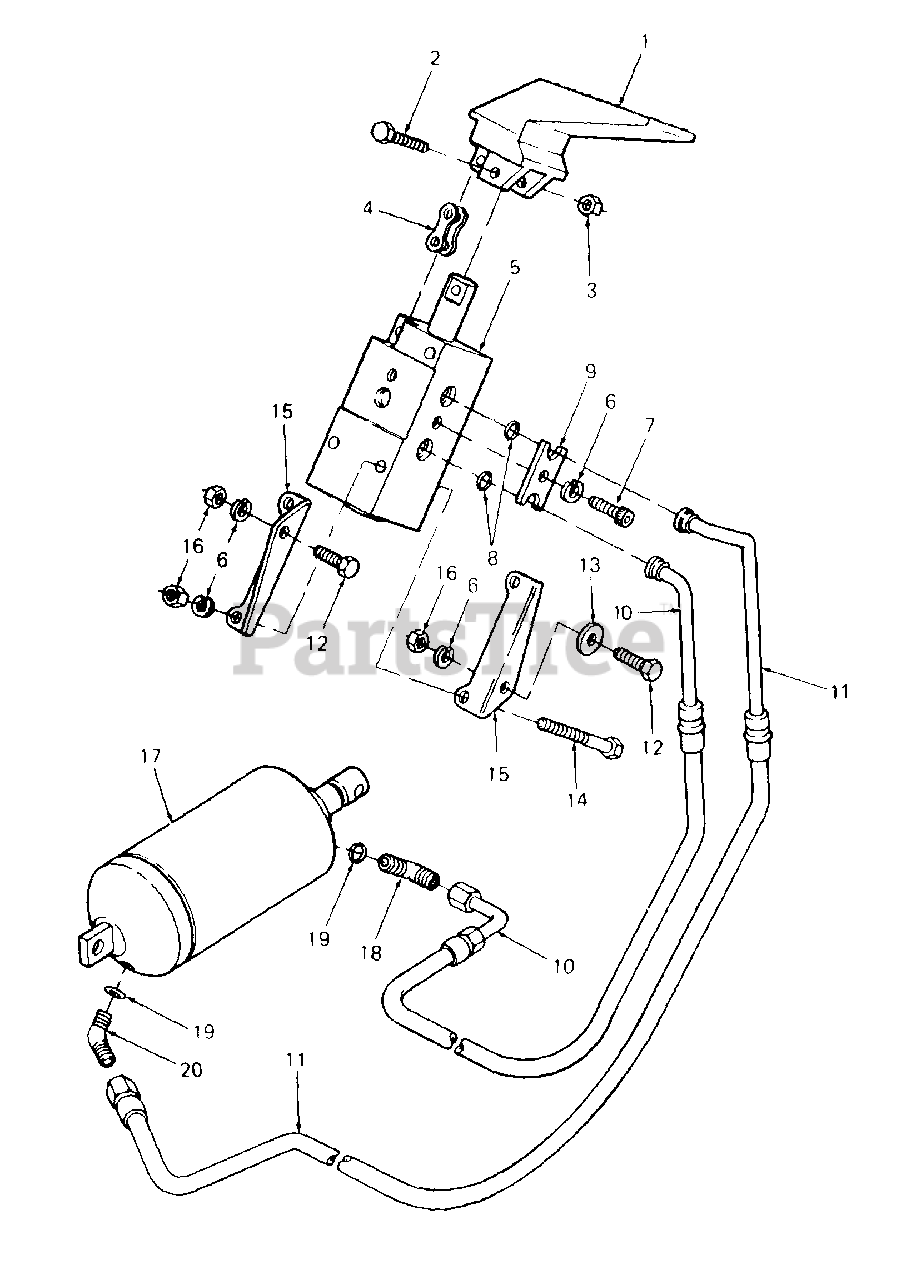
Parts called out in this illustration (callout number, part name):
1	Handle, Valve
2	Screw, Hex Cap, #10-24 X 1.0 Lg
3	Nut, Hex Center Lock, #10-24
4	Link, Chain
5	Valve, Lift
6	Washer, Lock, 1/4
7	Screw, Socket Hd Cap, 1/4-20 X .62 Lg GR8
8	O-Ring, .301 X .070 Dia
9	Clamp, Double
10	Hose, Cylinder-Contracting
11	Hose, Cylinder-Extending
12	Screw, Hex Cap, 1/4-20 X .62 Lg GR5
13	Washer, Bell, .265 X .75 X .62 Thk
14	Screw, Hex Cap, 1/4-20 X 2.25 Lg
15	Bracket, Valve Mtg
16	Nut, Hex, 1/4-20 GR5
17	Cylinder, Hydraulic
18	Elbow, 90 Deg w/O-Ring
19	O-Ring, 1/4 OD Tube
20	Elbow, 45 Deg w/O-Ring
